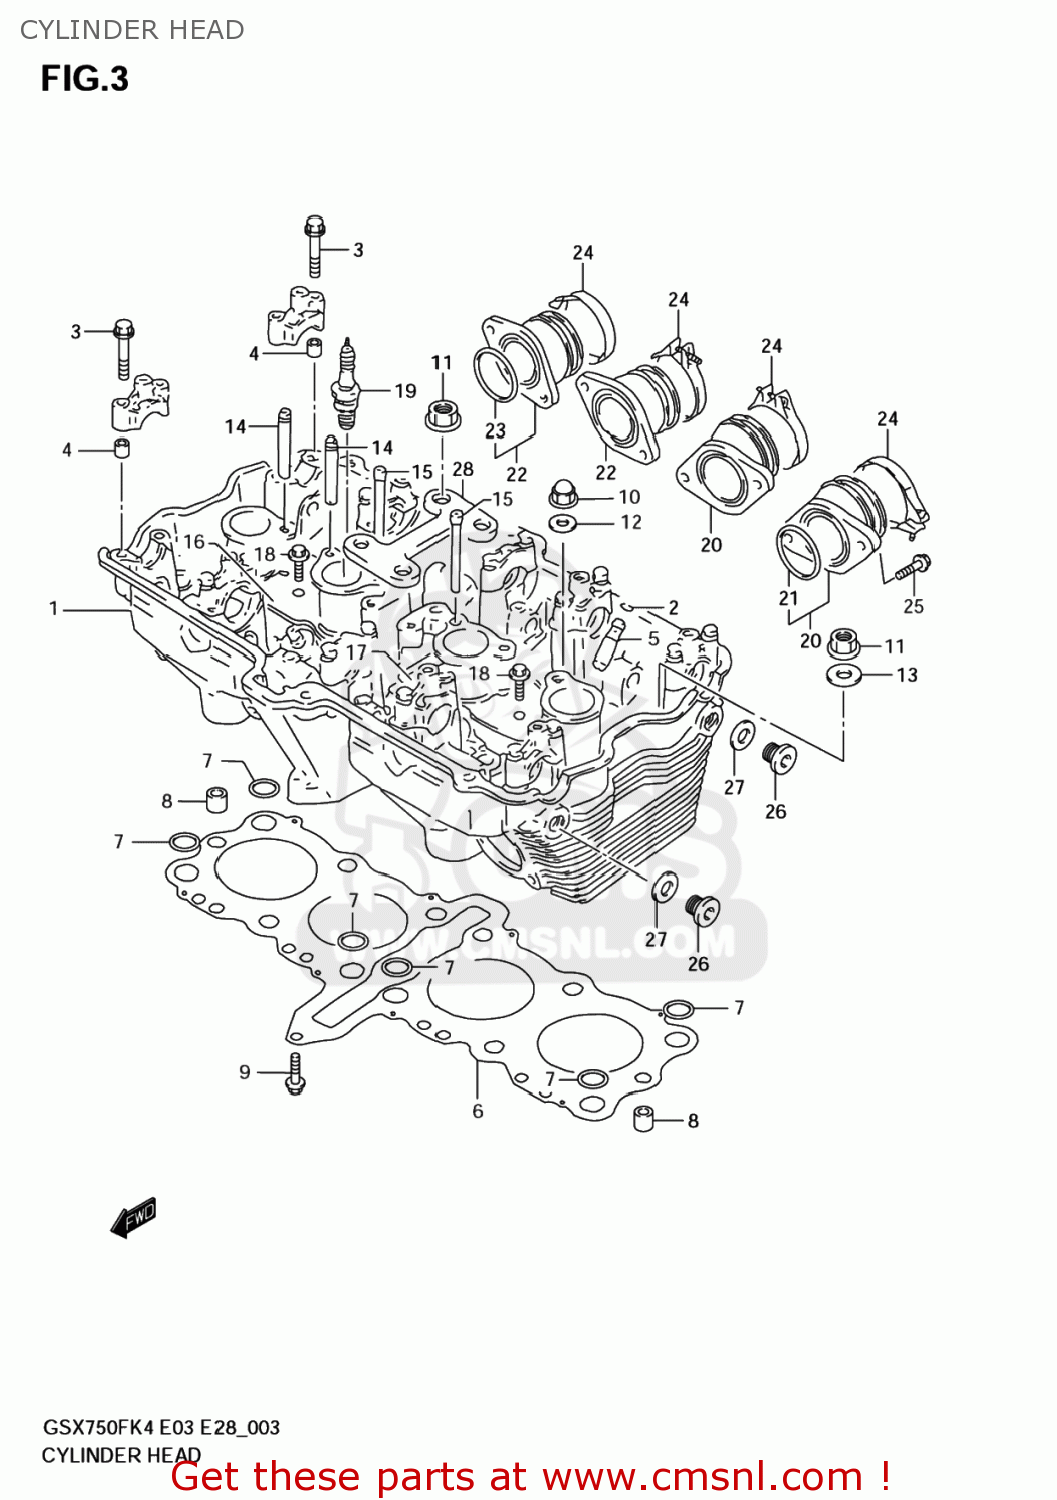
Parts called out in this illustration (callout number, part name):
1	HEAD ASSY,CYLINDER
2	RING,SNAP
3	BOLT(6X39)
4	PIN(6.2X8X11)
5	GUIDE,VALVE
6	GASKET,CYLINDER HEAD (NAS)
7	O RING,HEAD GASKET
8	PIN
9	BOLT
10	NUT
11	NUT
12	GASKET(10.2X20X2).3 (NAS)
13	WASHER (10.5X22X2.3)
14	PIPE,OIL NO.1
15	PIPE,OIL NO.3
16	PLATE,OIL PIPE,R
17	PLATE,OIL PIPE,L
18	BOLT
19	PLUG,SPARK(CR9EK)
20	PIPE ASSY,INTAKE NO.1
21	O RING(D:2.4,ID:41.7)
22	PIPE ASSY,INTAKE NO.3
23	O RING(D:2.4,ID:41.7)
24	CLAMP
25	BOLT MAGNETO S
26	PLUG
27	GASKET(13.8X18.8X4.8) (NAS)
28	PLATE,HEAD REINF
